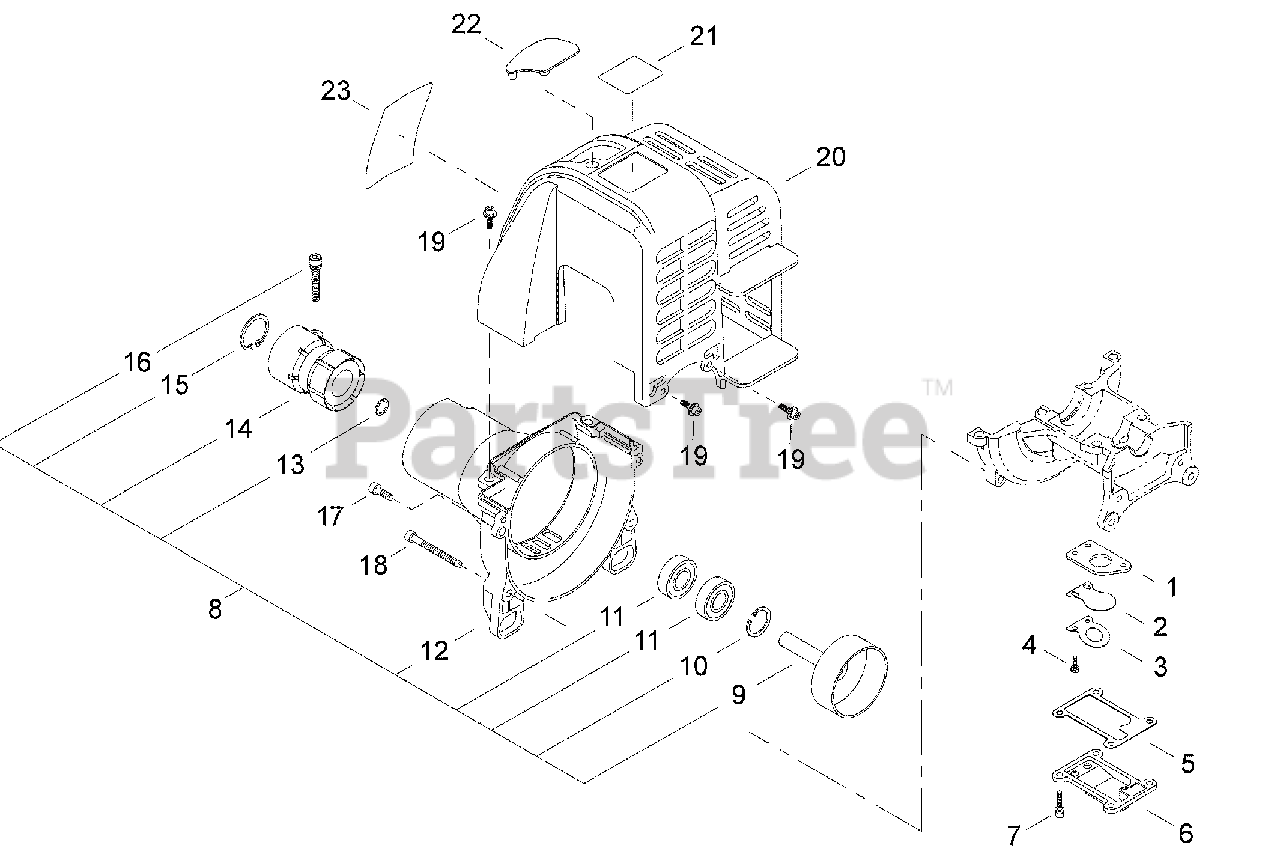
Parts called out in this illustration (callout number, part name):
1	PLATE, REED BACKING
2	VALVE, REED
3	STOP, REED VALVE
4	SCREW - 3X10
5	GASKET, REED VALVE
6	COVER, REED VALVE
7	SCREW - 4X12
8	FAN CASE ASSY
9	DRUM, CLUTCH
10	RING, RETAINING - 26
11	BEARING, BALL - 6000
12	CASE, FAN
13	RING, RETAINING
14	CUSHION
15	RING, RETAINING - 40
16	SCREW - 5X22
17	SCREW - 5X16
18	SCREW - 5X45
19	SCREW - 4X16
20	COVER, ENGINE
21	LABEL - MODEL B3000
22	COVER, SPARK PLUG
23	LABEL - E4
